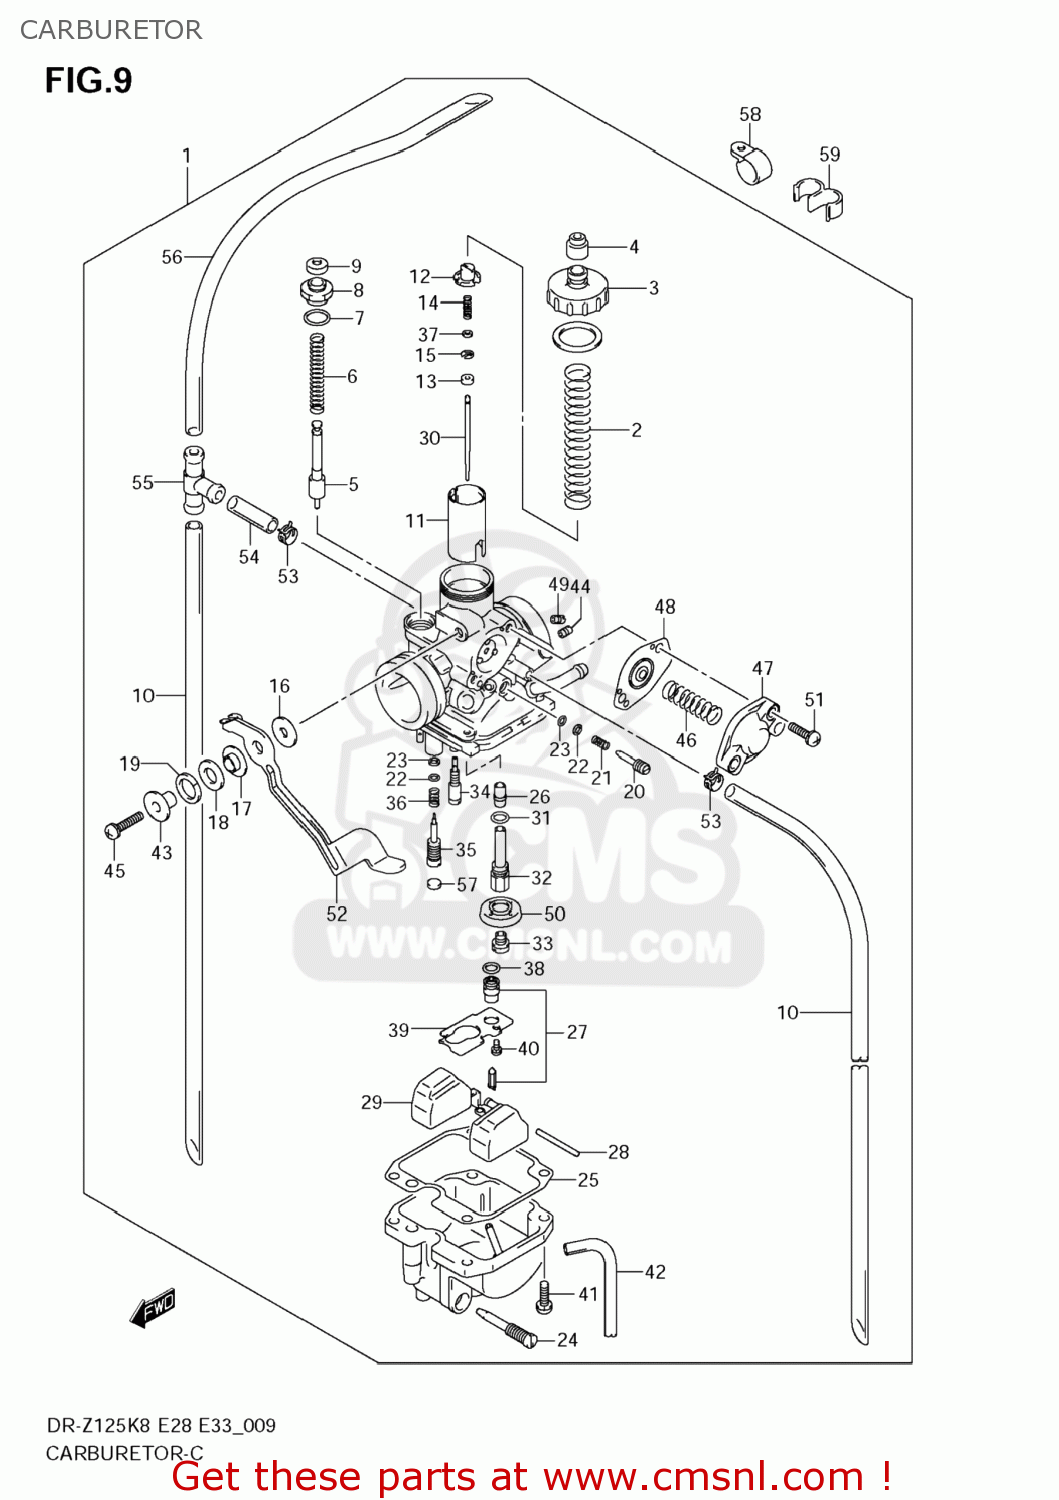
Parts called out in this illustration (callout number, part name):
1	CARBURETOR ASSY
2	SPRING
3	MIXING CAP ASSY
4	CAP
5	PLUNGER ASSY
6	SPRING
7	O RING
8	GUIDE SCREW,PLUNGER
9	CAP,STARTER VALVE
10	HOSE(5X8X475)
11	VALVE,PISTON
12	HOLDER
13	RING
14	SPRING
15	E RING
16	PLATE
17	RING
18	WASHER
19	WASHER,LOCK
20	SCREW,ADJUST
21	SPRING
22	WASHER
23	O RING,PILOT AIR SCREW
24	SCREW
25	GASKET (NAS)
26	JET,NEEDLE
27	VALVE ASSY,NEEDLE
28	PIN,FLOAT
29	FLOAT ASSY
30	JET,NEEDLE(5HGM74)
31	O RING
32	JET,HOLDER
33	JET,MAIN(102.5)
34	JET,PILOT(17.5)
35	ADJUSTER
36	SPRING
37	WASHER
38	O RING
39	PLATE
40	SCREW
41	SCREW
42	HOSE(3X5X650)
43	RING
44	JET,AIR(85.0)
45	SCREW
46	SPRING
47	COVER ASSY
48	DIAPHRAGM ASSY
49	JET,POWER(145)
50	HOLDER
51	SCREW
52	LEVER
53	CLIP
54	HOSE(5X8X25)
55	NIPPLE
56	HOSE(5X8X375)
57	PLUG
58	CLAMP
59	CLAMP
